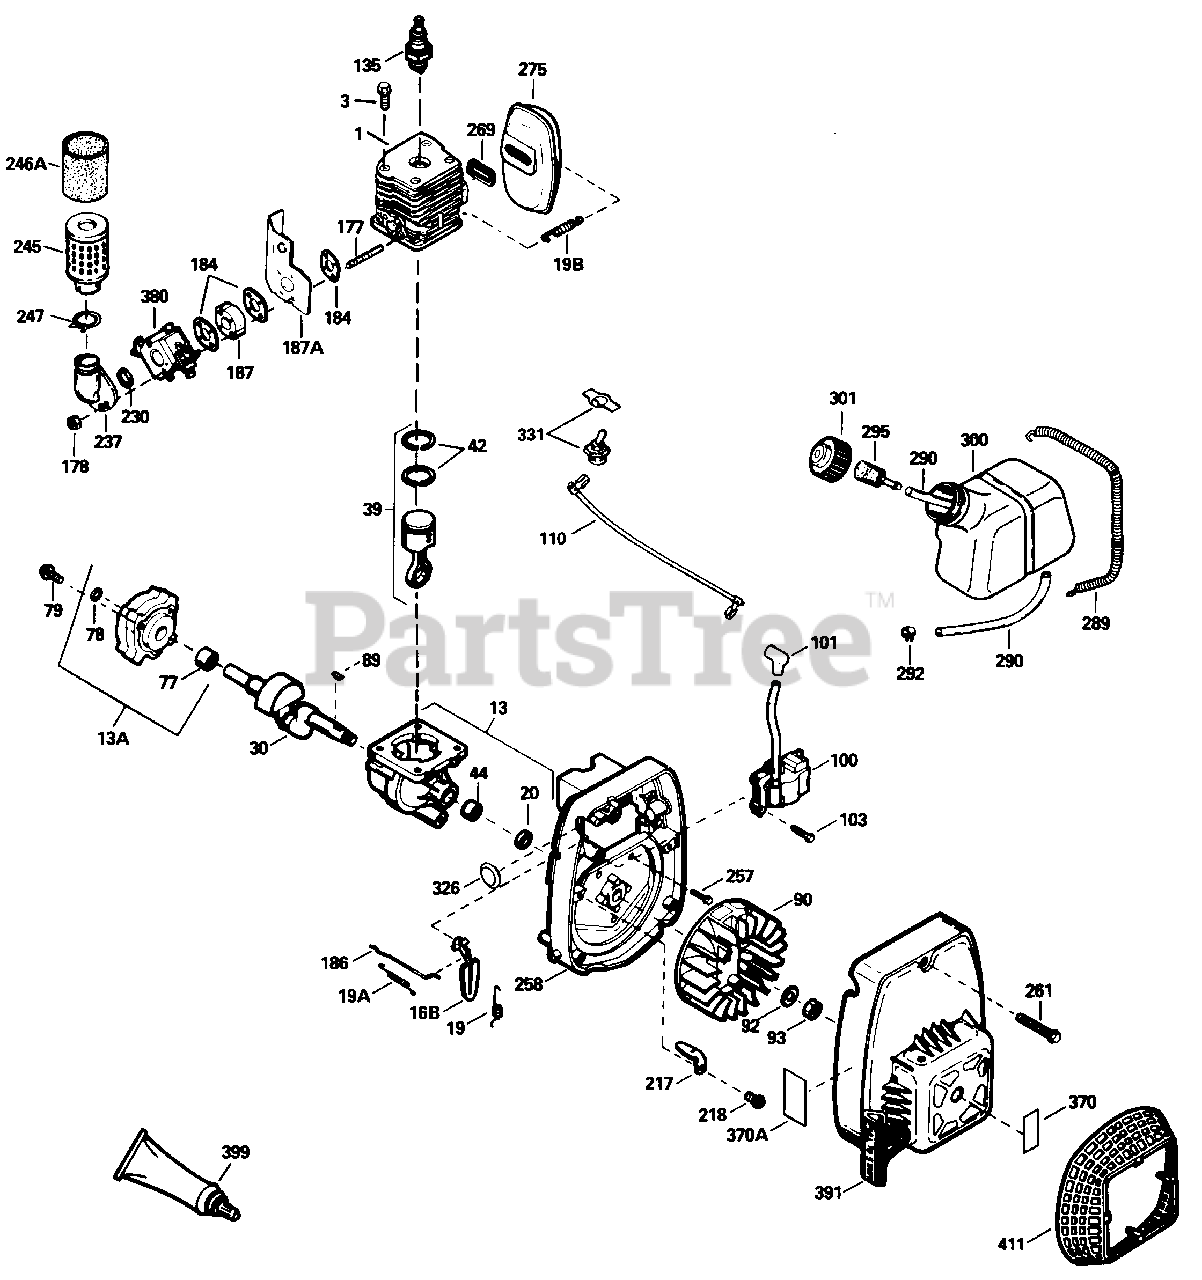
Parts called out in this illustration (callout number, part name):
3	Screw, Torx Int. Drive Flanged Hd., 1/4-20 x 43/64
13	Crankcase Ass'y.
13A	Cover Ass'y., Crankcase
19	Spring, Governor
19A	Spring, Back Lash
19B	Spring, Muffler
30	Crankshaft
39	Piston & Rod Ass'y.
42	Ring Set, Piston
44	Bearing, Cartridge
77	Bearing, Cartridge
79	Screw, Hex Washer Hd. Taptite, 1/4-20 x 3/4
89	Key, Flywheel
92	Washer, Belleville
93	Nut, Flywheel (3/8-24)
100	Lamination Ass'y. (Solid State)
101	Cover, Spark Plug
103	Screw, Hex Hd. Sems, 10-24 x 1
110	Wire, Cut-Off
135	Plug, Spark
177	Stud, Air Cleaner
178	Nut, Lock, 10-24
184	Gasket, Carburetor
186	Link, Governor
187	Spacer, Carburetor
187A	Baffle, Carburetor
217	Lever, Speed Adjusting
218	Screw, Hex Washer Hd. Taptite, 8/32 x 1/2
230	"O"-Ring, Air Cleaner
237	Adapter, Air Cleaner
245	Filter, Air
246A	Filter, Pre-Air
247	Clamp, Air Cleaner
257	Screw, Hex Washer Hd. Taptite Thread Rolling, 10-24 x 1/2
258	Base, Blower Housing
261	Screw, Hex Washer Hd. Taptite Thread Rolling, 8/32 x 1-9/16
269	Gasket, Exhaust
289	Spring, Fuel Tank
292	Clamp, Fuel Line
295	Fitting & Filter Ass'y., Fuel
300	Tank, Fuel (1 Pint)
301	Cap Ass'y., Fuel
331	Switch, Toggle
370	Decal, Name
370A	Decal, Instruction
380	Carburetor
391	Starter & Housing Ass'y., Rewind
399	Gasket Eliminator
411	Screen, Starter
